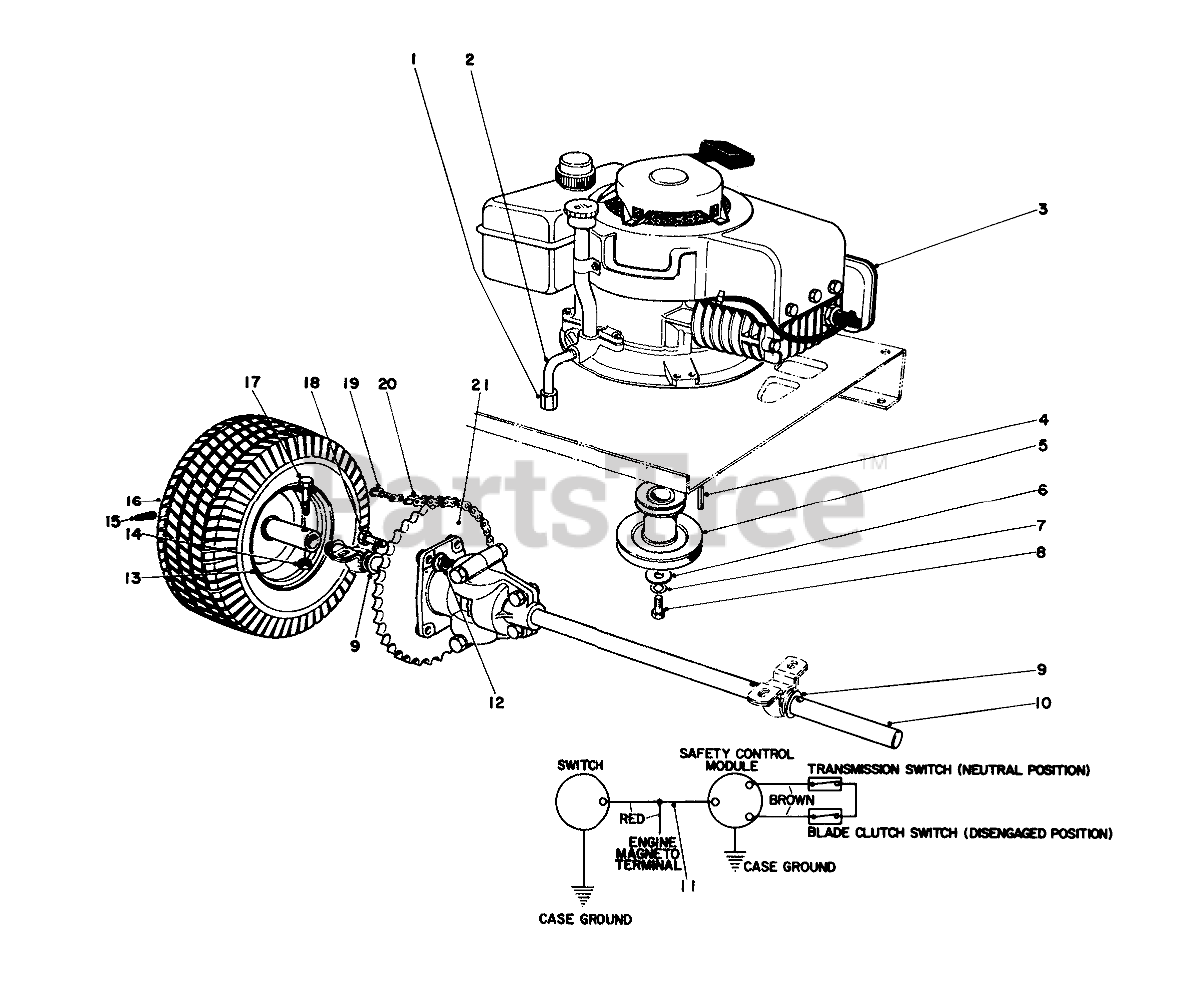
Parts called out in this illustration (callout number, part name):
1	Hex Cap
2	Elbow-Oil Drain
3	Engine
5	Pulley
6	Washer
7	WASHER-LOCK
8	SCREW-HH
9	WASHER
10	Differential
11	Wiring Harness
12	NUT-LOCK, CONE
14	NUT-LOCK, CONE
15	STEM-VALVE
16	Tire
17	SCREW-HH
18	SCREW-HH
19	LINK-CONNECTING
20	Chain
21	Sprocket
